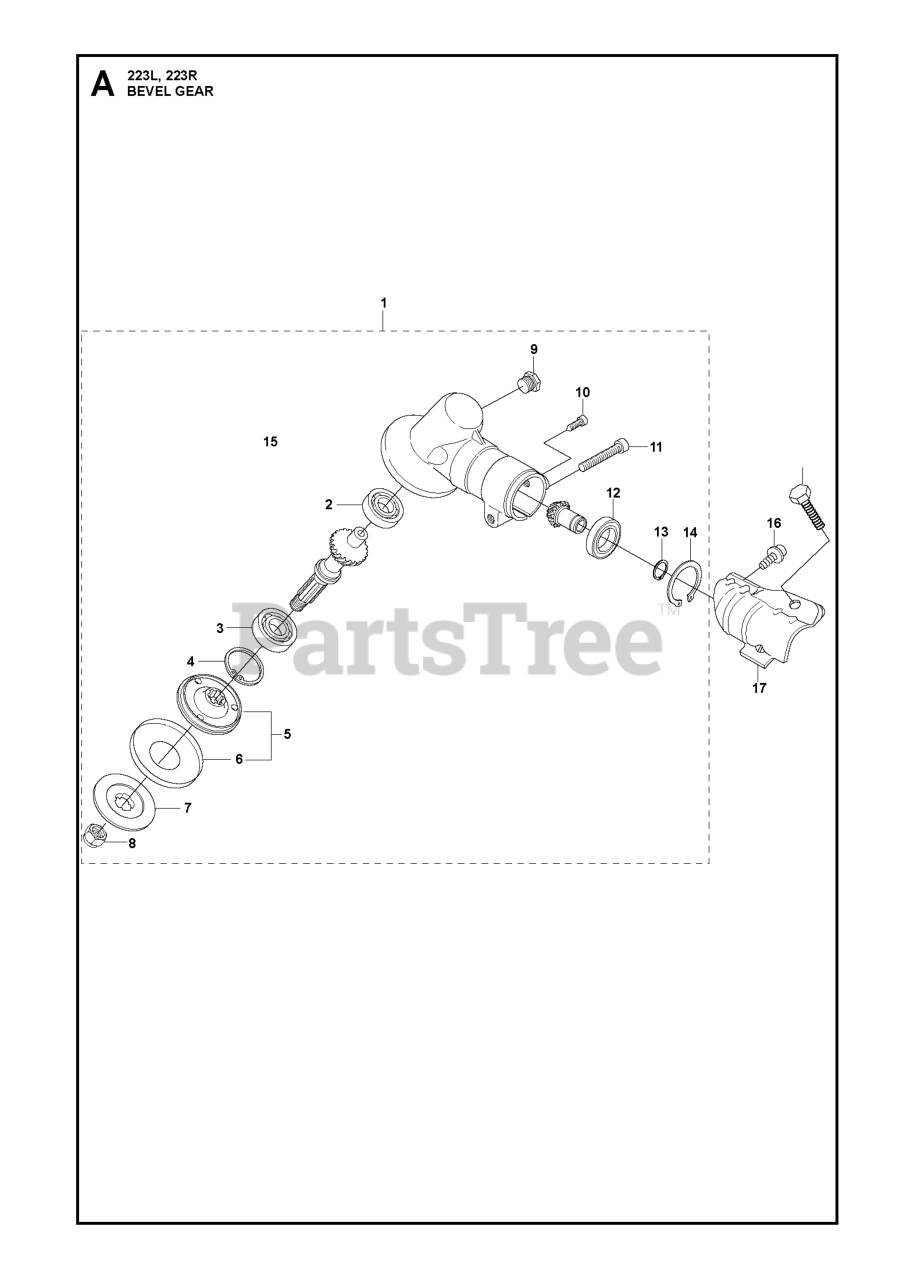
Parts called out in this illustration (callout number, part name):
1	SEAT SWITCH
1	ANGLE GEAR CPL 123L
2	SEAT W/ARMRESTS
2	BALL BEARING 8X22X7/608Z
3	BEARING
4	HCS 5/16C X 3/4
4	RETAINING RING SGH 28
5	NUT 3/8-16 NYLOC
5	DRIVE DISC
6	SCREW 3/8C X 3/4 HEX CAP
6	WASHER
7	WASHER.LOCK.HVY.HLCL.SPR.5/16
7	SUPPORT FLANGE
8	WASHER 5/16 FLAT
8	GEARHEAD NUT - BRUSHCUTTER
9	ARM, PROP, SEAT
10	SEAT SPRING
11	SPRING CAP
12	HCS 5/16C X 1
12	BALL BEARING 24X9X1/609ZR
13	RETAINING RING
14	NUT 5/16 NYLOC
14	RETAINING RING
15	NUT 5/16C WHIZ
15	SCREW M6S 6X20
17	RP BRACKET TRIMMER GUARD
